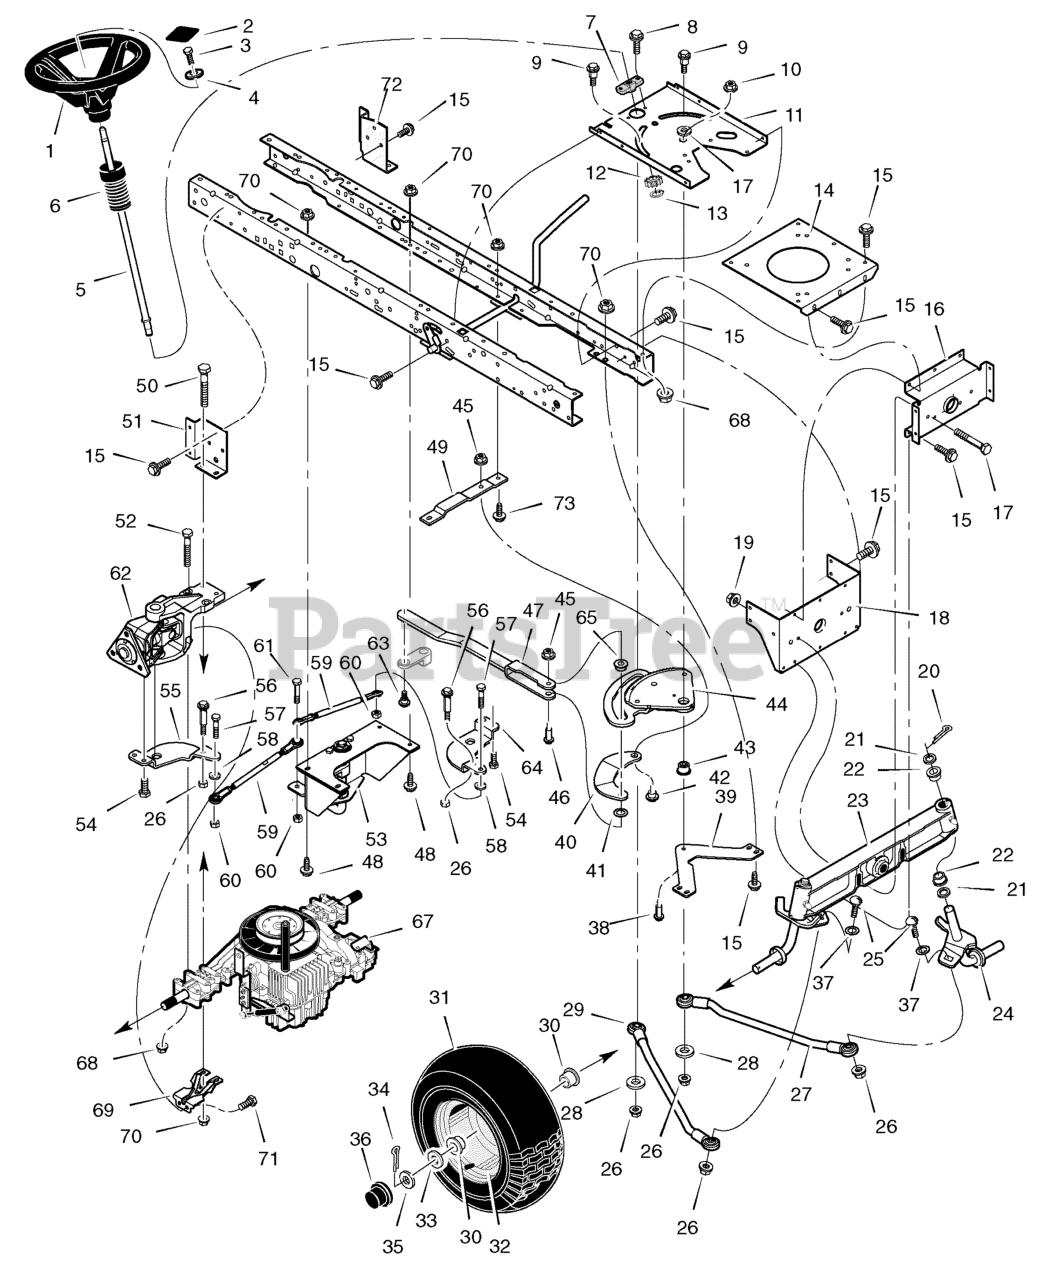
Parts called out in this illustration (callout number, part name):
1	Wheel, Steering
2	Cap, Steering Wheel
3	Screw, Hex
4	Washer
5	Shaft, Steering
6	Cover
7	Bearing, Lower Steering
8	Screw
9	Bolt, Shoulder
10	Nut, Flanged Lock
11	Plate, Steering
12	Gear, Pinion
13	Ring, Snap
14	Plate, Engine
15	Screw
16	Hanger, Axle
17	Bolt, Hex
18	Bracket, Rear Hanger
19	Nut, Flanged Lock
20	Pin, Cotter
21	Washer
22	Bearing, Steering
23	Axle, Front
24	Spindle Assembly, Left
25	Bolt, Carriage
26	Nut, Flanged Lock
27	Link, Left Drag
29	Link, Right Drag
30	Bearing, Front Wheel
31	Tire ONLY *
32	Wheel and Tire Assembly
33	Washer
34	Pin, Cotter
35	Washer
36	Hub Cap
37	Washer
38	Bolt, Hex
39	Support, Sector Gear
40	Follower, Cam
41	Washer
42	Bolt, Shoulder
43	Bearing, Sector Gear
44	Sector Gear & Cam Assembly
45	Nut. Flanged Lock
46	Bolt, Shoulder
47	Link, Primary Drag
48	Screw
49	Member, Cam Cross
50	Bolt, Hex
51	Bracket, Right Transaxle
52	Bolt, Shoulder
53	Pivot Assembly, Rear
54	Screw
55	Arm, Right Rear
56	Bolt, Shoulder
57	Bolt, Hex
58	Washer, Split Lock
59	Rod Assembly, Tie
60	Nut, Lock
61	Bolt, Hex
62	Steering Assembly, Rear
63	Bolt, Shoulder
64	Arm, Left Rear
65	Bushing, Cam
67	Transaxle
68	Nut, Flanged Lock
69	Bracket, Transaxle Support
70	Locknut, Flange
71	Screw
72	Bracket, Left Transaxle
73	Screw
